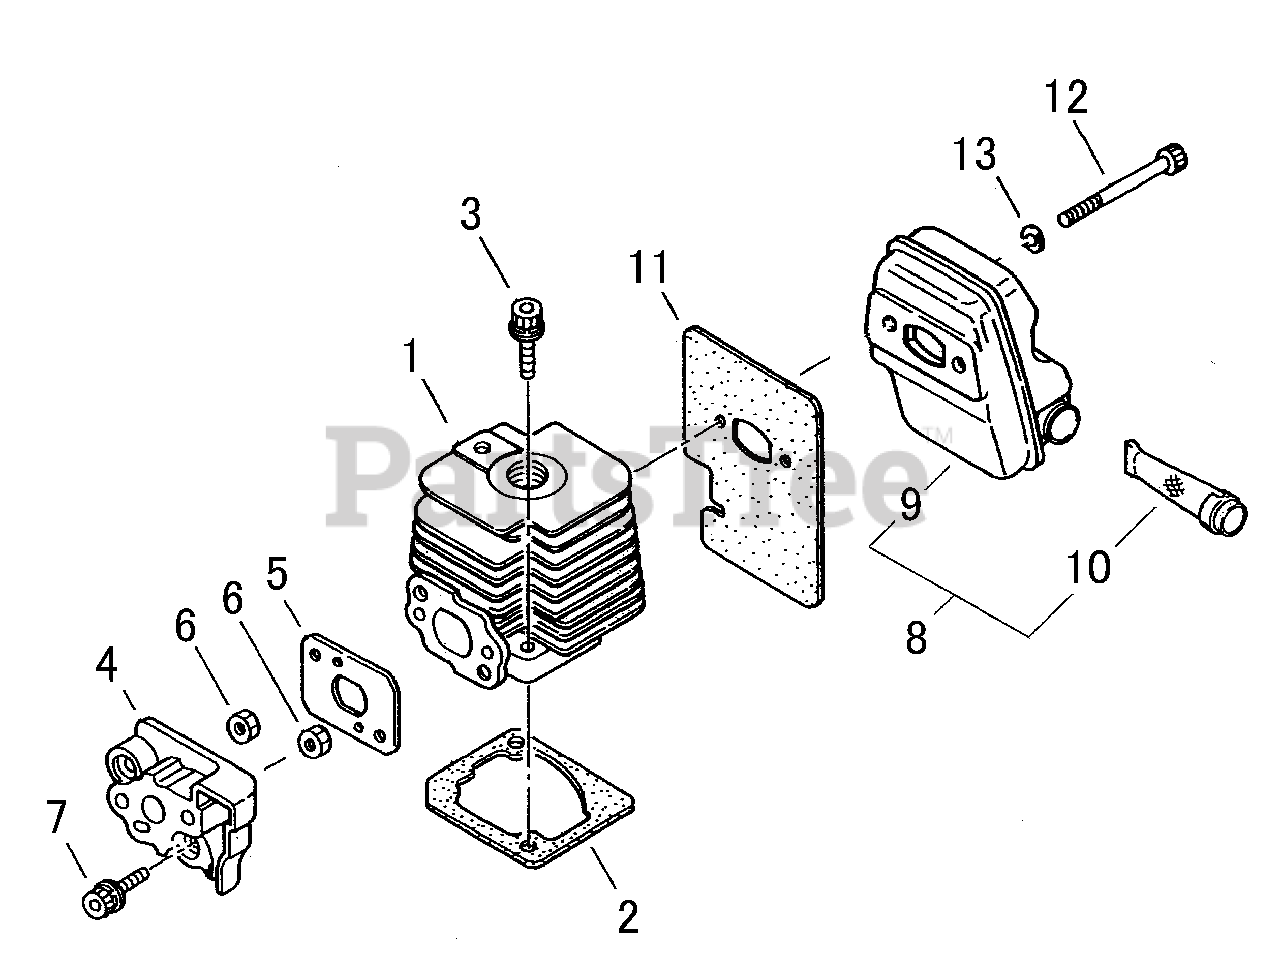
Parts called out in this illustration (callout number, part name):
1-1	CYLINDER
2	GASKET, CYLINDER
3	BOLT M5×25
4	INSULATOR, INTAKE
5	GASKET
6	NUT M5×6.3
7	BOLT M5×25
8	MUFFLER ASSY
9	MUFFLER
10	SCREEN, SPARK ARRESTER
11	HEAT SHIELD, EXHAUST
12	BOLT 5×40
13	WASHER, FLAT 5.5×10×0.8
